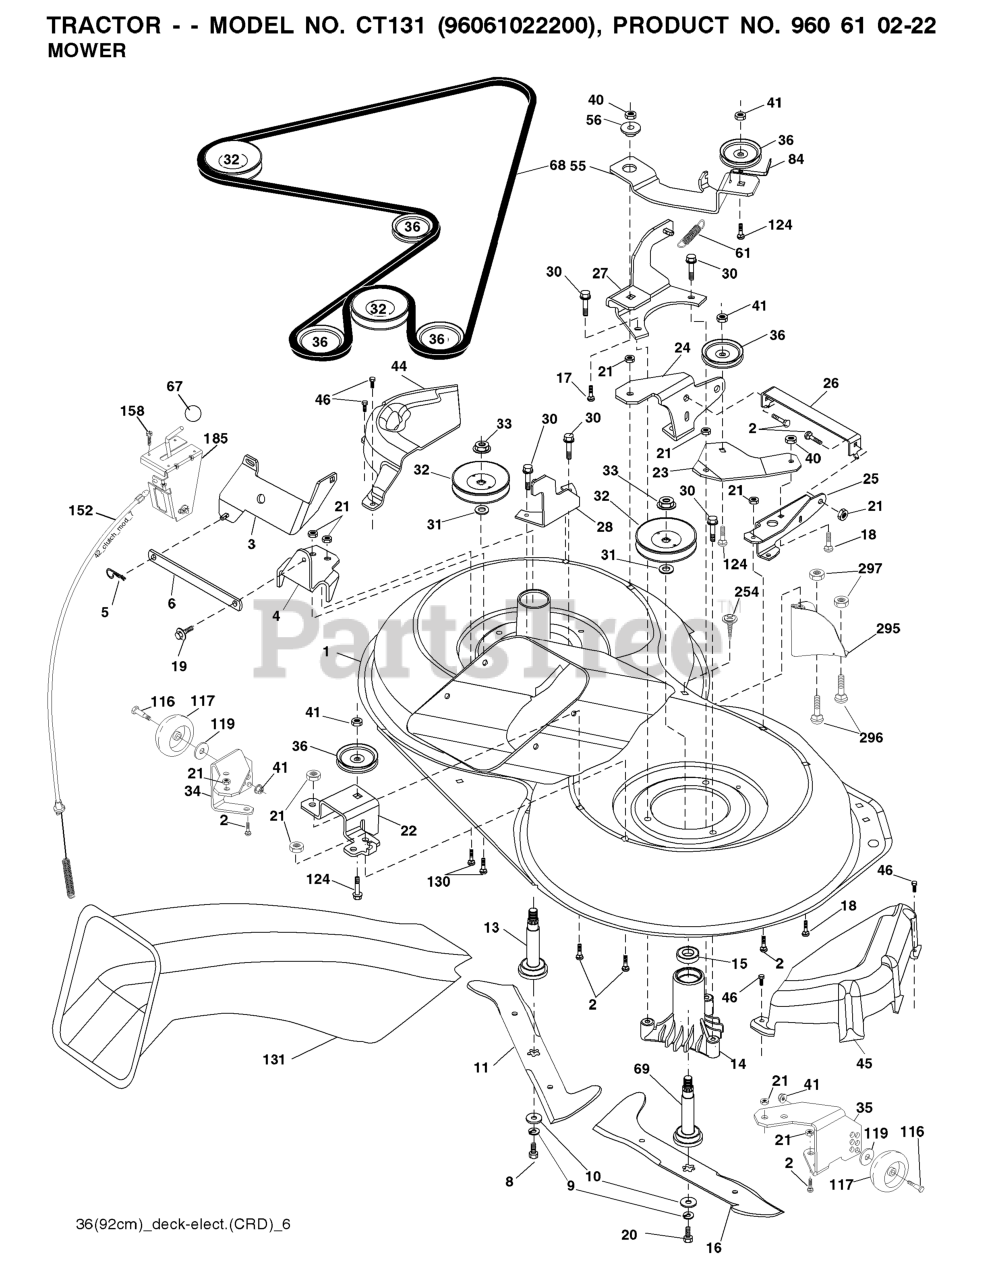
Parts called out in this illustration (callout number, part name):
2	RP BOLT 5/16-18 X3/4 ZN/YEL GR
5	RETAINER-SPRNG RB
6	BAR.SWAY.92.CRD
8	BOLT.3/8-24X1.25 GR8
9	LOCKWASHER
10	WASHER.BLADE
13	SHAFT ASM VENT
14	HOUSING.MANDREL.VENTED (MACHD)
17	BOLT.3/8-14X1.25
19	BOLT SHD 5/16-18
20	BOLT.3/8-24X1.25GR8. LHTHRD
21	LOCKNUT
26	SUPPORT
30	SCREW, WASHER HEAD
31	WASHER.SPACER.MANDREL
32	PULLEY MANDREL
33	NUT.FLANGE.LOCK.TOP
36	PULLEY.IDLER.4.25
41	NUT LOCK FLG 3/8-16 UNC
45	COVER.MANDREL.RH.CRD
46	SCREW.1/4-20X5/8
55	ARM.IDLER.92 CRD.2006
56	SPACER.RETAINER.MOWER
61	SPRING
67	KNOB T (3/8 HOLE)
68	BELT.DRIVE.92CM.CRD.2006
69	SHAFT.ASM.W/LWR.BRG.RH.THREAD
84	KEEPER, BELT IDLER
116	BOLT.SHOULDER.3/8-16X3-5/8.
117	RP WHEEL. GUAGE RALLY
119	WASHER
124	BOLT.3/8-16X1.50
130	BOLT.CARR.SQNK.5/16-18UNC.X3/4
131	CHUTE BAGGER
158	SCREW
185	HEAD ASM. CABLE CLUTCH
254	SCREW 3/8-16X1
296	BOLT
297	NUT CENTERLOCK
